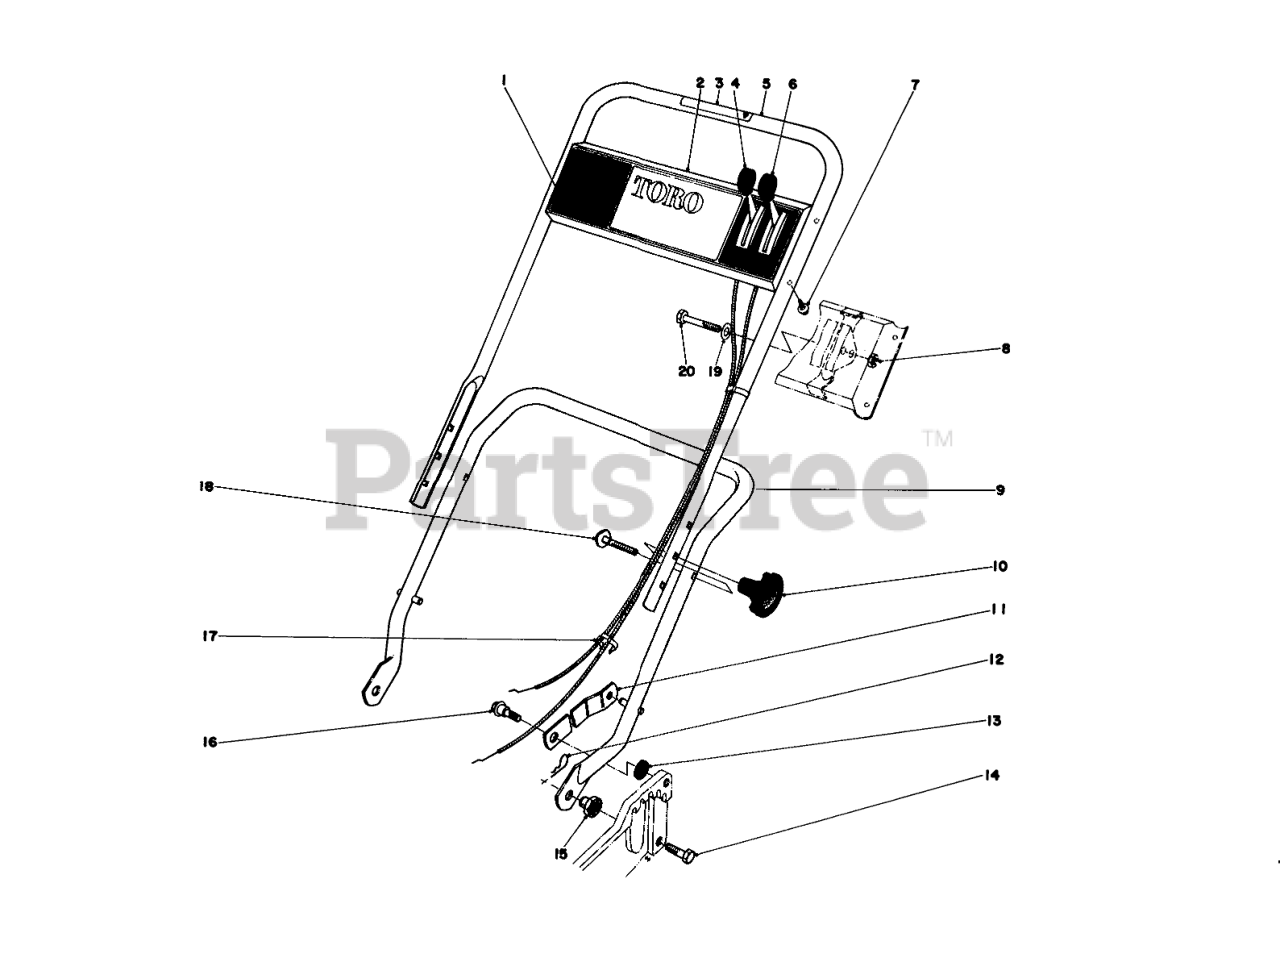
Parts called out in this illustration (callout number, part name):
1	Decal Control Plate
2	Control Plate
3	Decal
4	Throttle Control
5	Upper Handle
6	Traction Control
7	Screw
9	Lower Handle
11	HANDLE LATCH
12	PIN-COTTER, HAIR
13	SPACER
14	SCREW-HH
15	HANDLE PIVOT NUT
16	SCREW-SHOULDER
18	HANDLE SCREW
19	WASHER-FLAT
20	SCREW-HH
